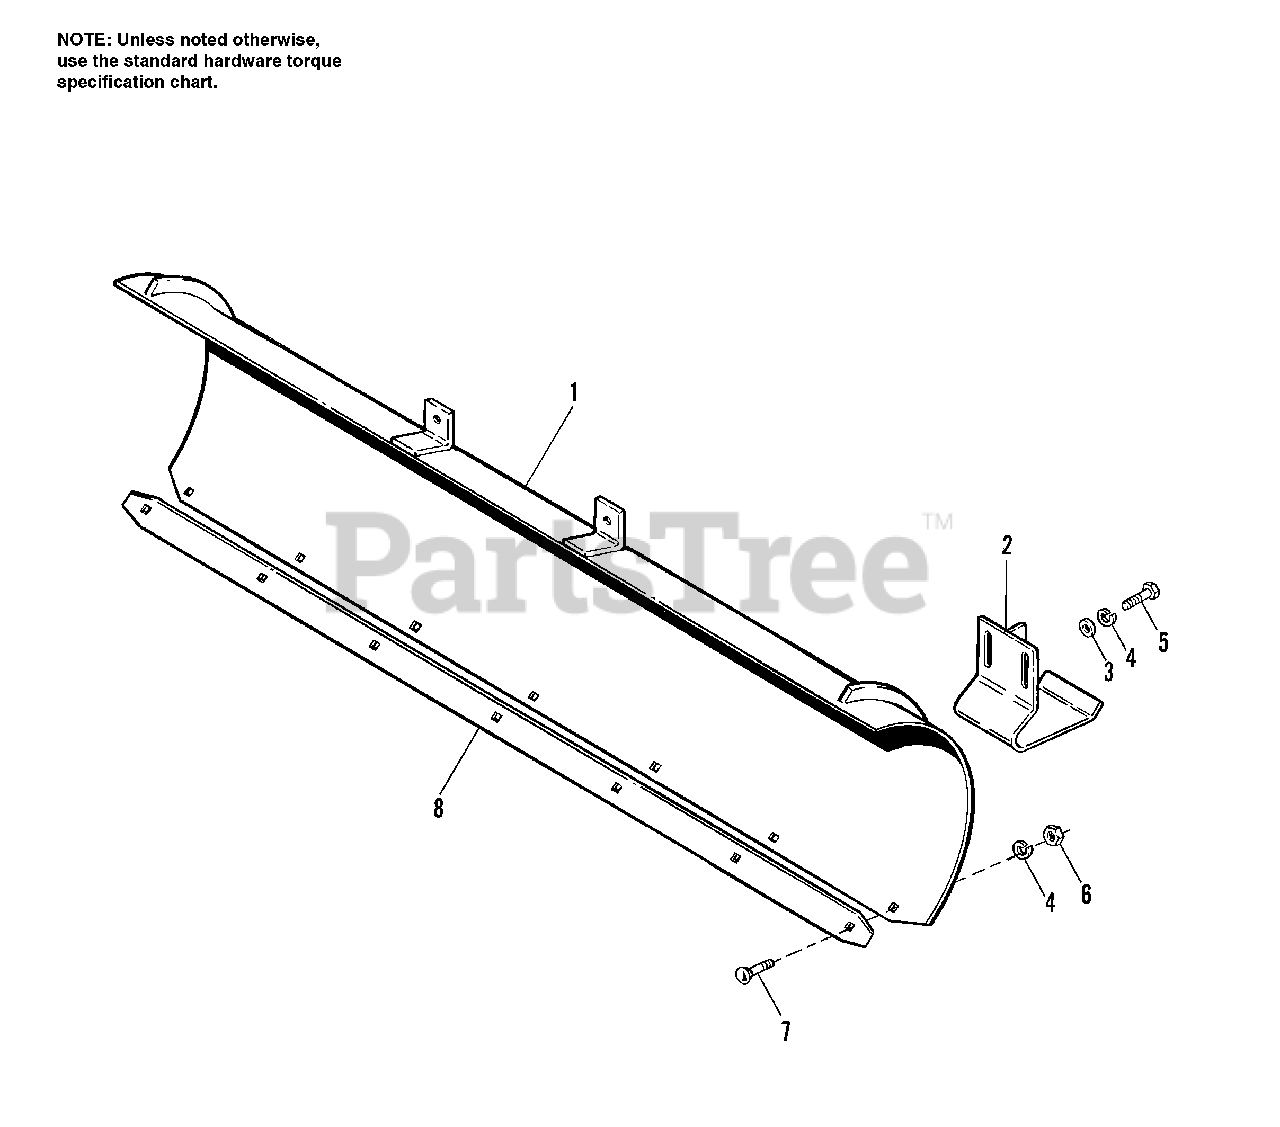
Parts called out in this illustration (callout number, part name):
1	BLADE ASSEMBLY, 60"
2	SHOE ASSEMBLY
3	WASHER, 3/8
4	WASHER, Lock, 3/8
5	CAPSCREW, Hex Hd, 3/8-16 x 3/4
6	NUT, Hex, 3/8-16
7	CARRIAGE BOLT, 3/8-16 x 1
8	PLATE, Wear
